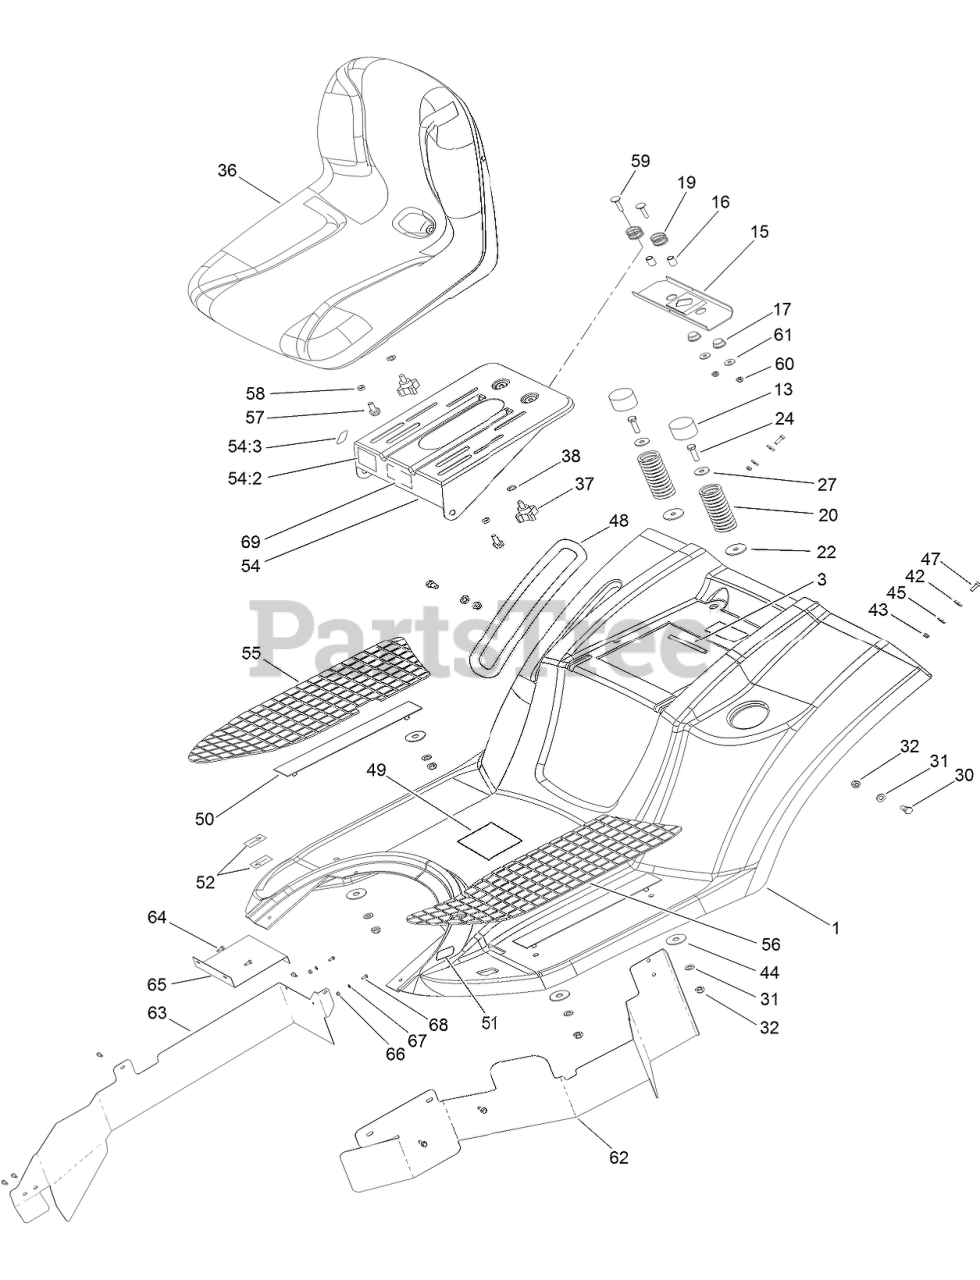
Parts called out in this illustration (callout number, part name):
1	FENDER-REAR
3	PURL-RUBBER, BATTERY
13	CAP-HUB
15	BRACKET
16	SPACER-SPLIT
17	BUSHING
19	SEAT-SPRING
20	SPRING-SEAT
22	WASHER
24	SCREW-HH
27	WASHER-PLAIN
30	SCREW-SUPPORT, SEAT
31	WASHER-PLAIN
32	NUT-LOCK, NI
37	KNOB-ADJUST
38	WASHER-SPRING
42	WASHER-FLAT
43	NUT-LOCK
44	WASHER-RUBBER
45	WASHER-RUBBER
48	DECAL-HEIGHT OF CUT
49	DECAL-DANGER
50	HOLDER
51	DECAL-BRAKE, PARKING
52	DECAL-TRAVEL
54	BRACKET-SUPPORT, SEAT
54:2	DECAL-DANGER
54:3	DECAL-SWITCH
55	MAT-FOOT, RH
56	MAT-FOOT, LH
57	SCREW-HHF
58	SPACER
59	SCREW-CARR
60	NUT-LOCK
61	WASHER-FLAT
62	COVER-BELT, LEFT
63	COVER-BELT, RIGHT
64	SCREW-TAP
65	COVER-BELT, TOP
66	NUT-HEX
67	Washer
69	DECAL-DANGER
